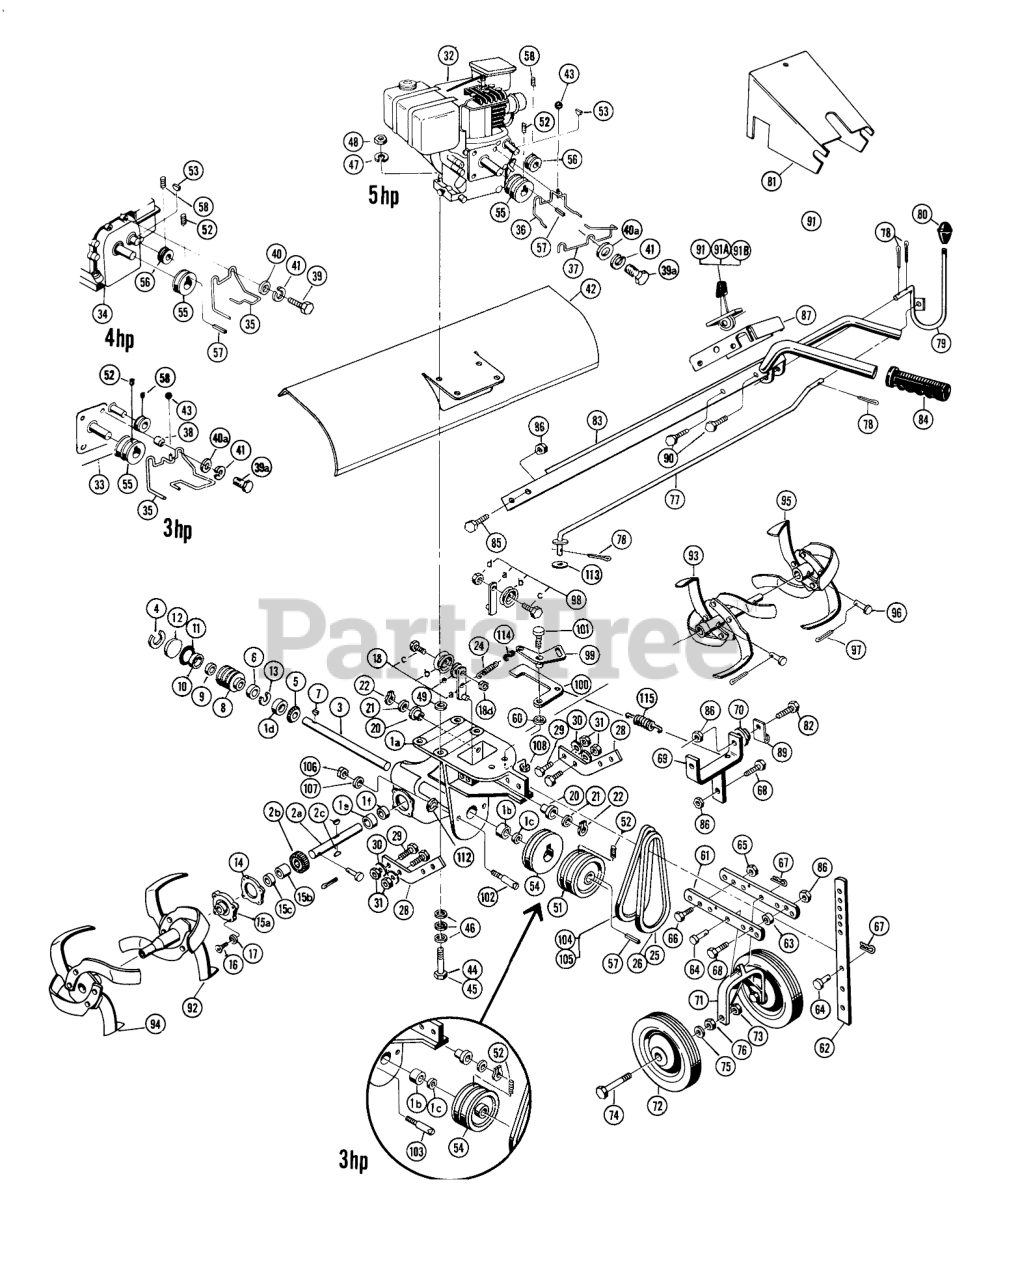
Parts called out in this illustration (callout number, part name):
2	Worm Wheel Assembly (Consists of)
3	WORM SHAFT
4	RETAINER RING
5	Bearing Cone
6	WORM SHF REAR SPACER
7	KEY-WOODRUFF
8	WORM GEAR
9	SPACER
10	Bearing
11	O Ring
13	INTRNL RETAINING RING
14	GASKET
15	Cap Assy (Consists of)
16	Screw
17	SCREW-HSH
18	Idler Pulley & Arm (Consists of)
19	Idler Pulley & Arm (Consists of)
20	IDLER BRG
21	Washer
22	RING-RETAINING, EXT
23	PLUG-PIPE, SQH
24	Spring
25	Belt
27	Nut
28	Handle Bracket
29	Leveler Head Bolt
30	WASHER-LOCK
31	NUT-HEX
32	Engine Tecumseh H50-9378 5HP
33	Engine Briggs & Stratton 100292 4HP
34	Engine
35	Belt Guide
36	Belt Guide
37	Belt Guide
38	SPACER
39	SCREW-HH
40	Washer
41	WASHER-LOCK
42	Shield
44	SCREW-HH
45	SCREW-HH
46	WASHER-FLAT
47	WASHER-LOCK
48	NUT-HEX
49	WASHER-FLAT
50	SCREW-HH
51	Pulley
52	Set Screw
53	KEY-WOODRUFF
54	Pulley
55	Engine Pulley
56	Pulley
57	KEY-SQUARE
58	SCREW-SET
59	SCREW-HH
60	Washer
61	Drawbar
62	DEPTH GAGE
63	Spacer
64	Pin
65	Nut
67	PIN-COTTER, HAIR
68	SCREW-HH
69	Support
70	Spacer
71	Wheel Bracket
72	Wheel
73	Nut
74	Axle
75	WASHER-FLAT
76	NUT-JAM
77	Clutch Rod
78	PIN-COTTER
79	Shift Lever
80	Knob
81	Pulley Cover
83	Handle Bar
84	Grip, Handle
87	Cover Handle
88	10-16 X 3/8 THDG SCREW
90	10-16 X 3/8 THDG SCREW
91	Throttle
92	Tines L. H. Inner (Consists of)
93	b. Tine R.H.
94	Tines L.H. Outer (Consists of)
95	Tines R.H. Outer (Consists of)
97	PIN-COTTER
98	Idler Pulley Arm Assy. (Consists of)
99	Bellcrank
100	Rev. Link
101	SCREW-SHOULDER, HH
102	Belt Guide
103	Belt Guide
104	V-BELT
106	NUT-HEX
107	WASHER-LOCK
110	SCREW-HH
111	WASHER-LOCK
112	Flatwasher
113	Washer
114	S Hook
115	Spring
